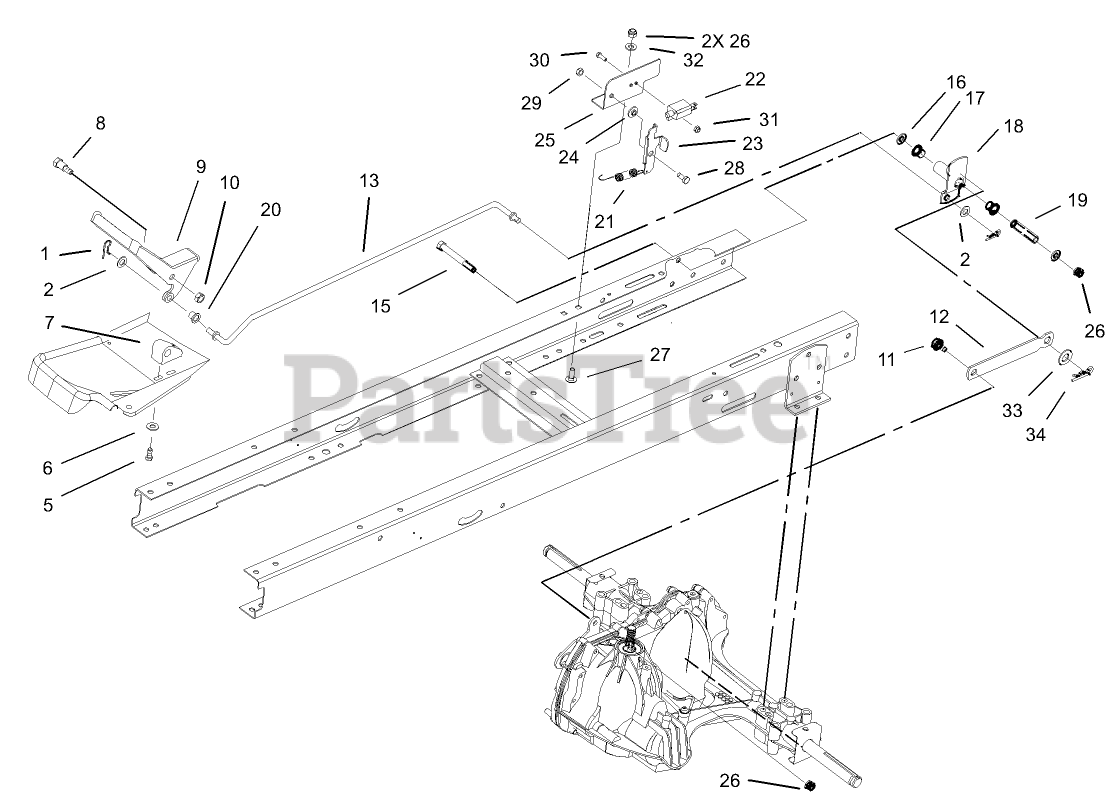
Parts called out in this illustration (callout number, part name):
2	WASHER-FLAT
5	SCREW-PLASTITE
6	WASHER-FLAT
7	BLOCK-PIVOT
8	SCREW-SHOULDER, HH
9	PEDAL-CONTROL, SPEED
11	BOLT-SHOULDER
12	LINK-CONTROL, SPEED
13	ROD-CONTROL, SPEED
15	SCREW-HH
16	WASHER-FLAT
17	BUSHING-NYLINER
18	PIVOT ASM
19	SPACER-PIVOT
20	BUSHING-FLANGED
21	SPRING-EXTENSION
22	SWITCH-POLE, SINGLE
23	BRACKET-PIVOT
24	WASHER-STEPPED
25	BRACKET-ADJUSTMENT
26	NUT-LOCK, NI
27	SCREW-CARR
28	SCREW-HHF
29	NUT-LOCK, NI
30	SCREW-SHH
31	NUT-LOCK
32	WASHER-PLAIN
33	WASHER-FLAT
34	PIN-HAIR
